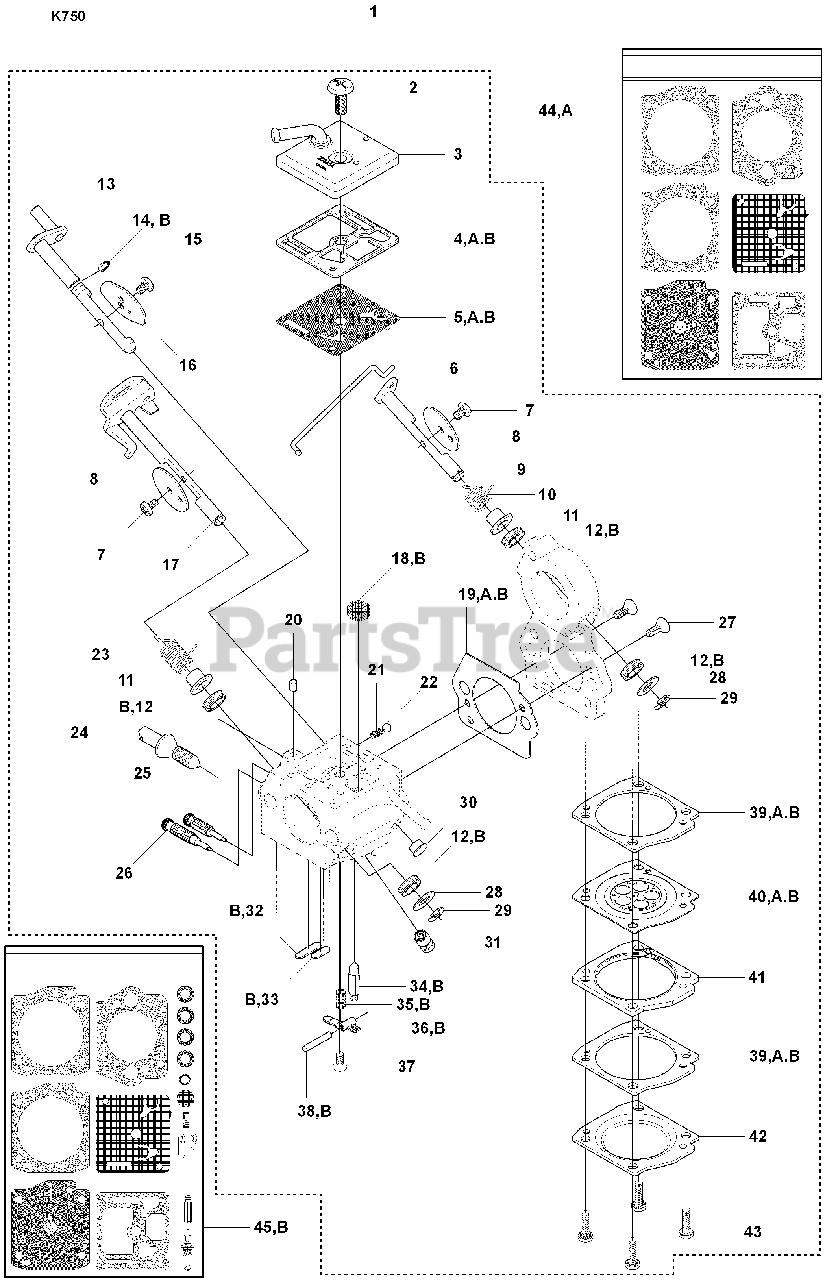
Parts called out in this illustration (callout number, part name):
1	CARBURETTOR
3	PUMP COVER
4	GASKET PUMP
5	DIAPHRAGM PUMP
9	SHAFT ASSY
13	SHAFT ASSY CHOKE
17	SHAFT ASSY
31	NOZZLE ASSY
32	PLUG WELCH
38	PIN RETAINING SCREW
40	DIAPHRAGM ASSY
44	GASKET KIT
45	GASKET KIT CARB
